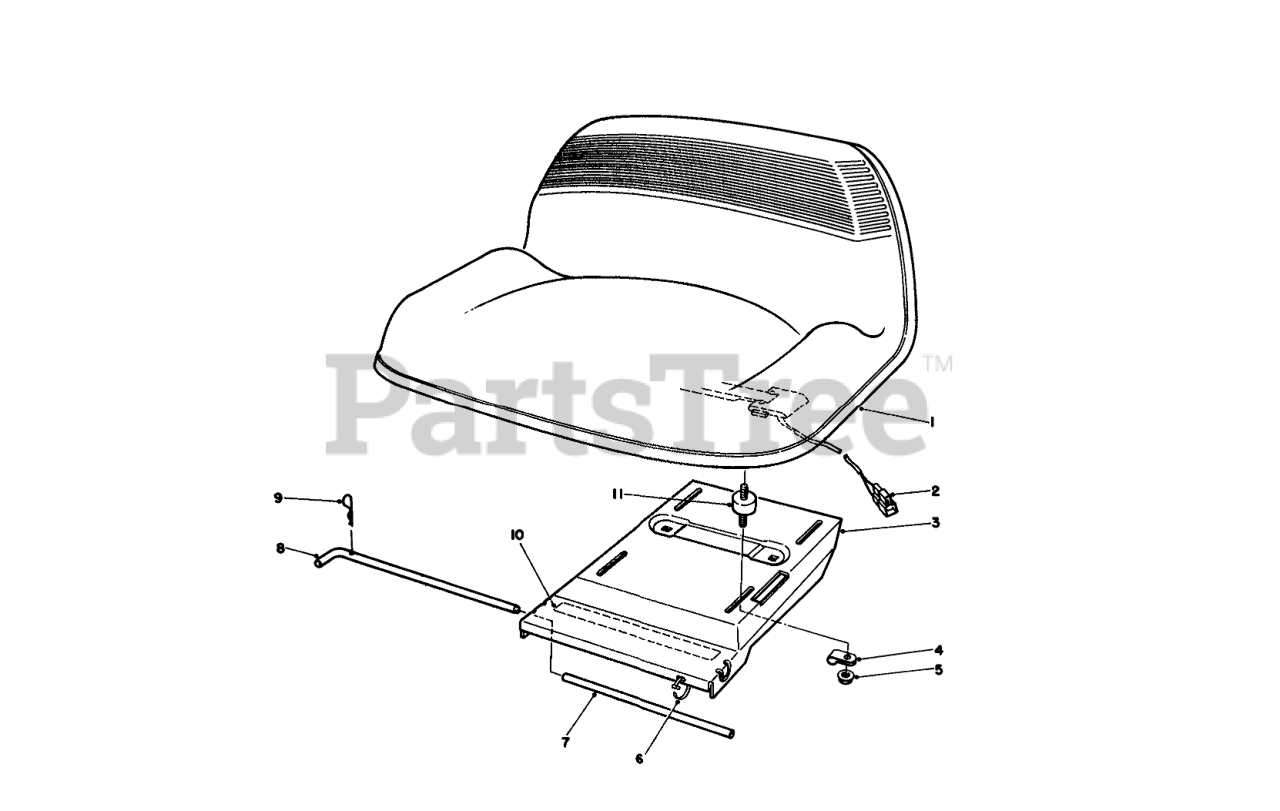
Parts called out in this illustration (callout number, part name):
1	Seat
2	SWITCH-SEAT
3	Base-Seat
4	CLAMP
5	NUT-HF
6	TIE-CABLE
7	TUBE-SEAT
8	ROD-SEAT BASE
9	PIN-COTTER
10	DECAL
11	ISOLATER-SEAT
